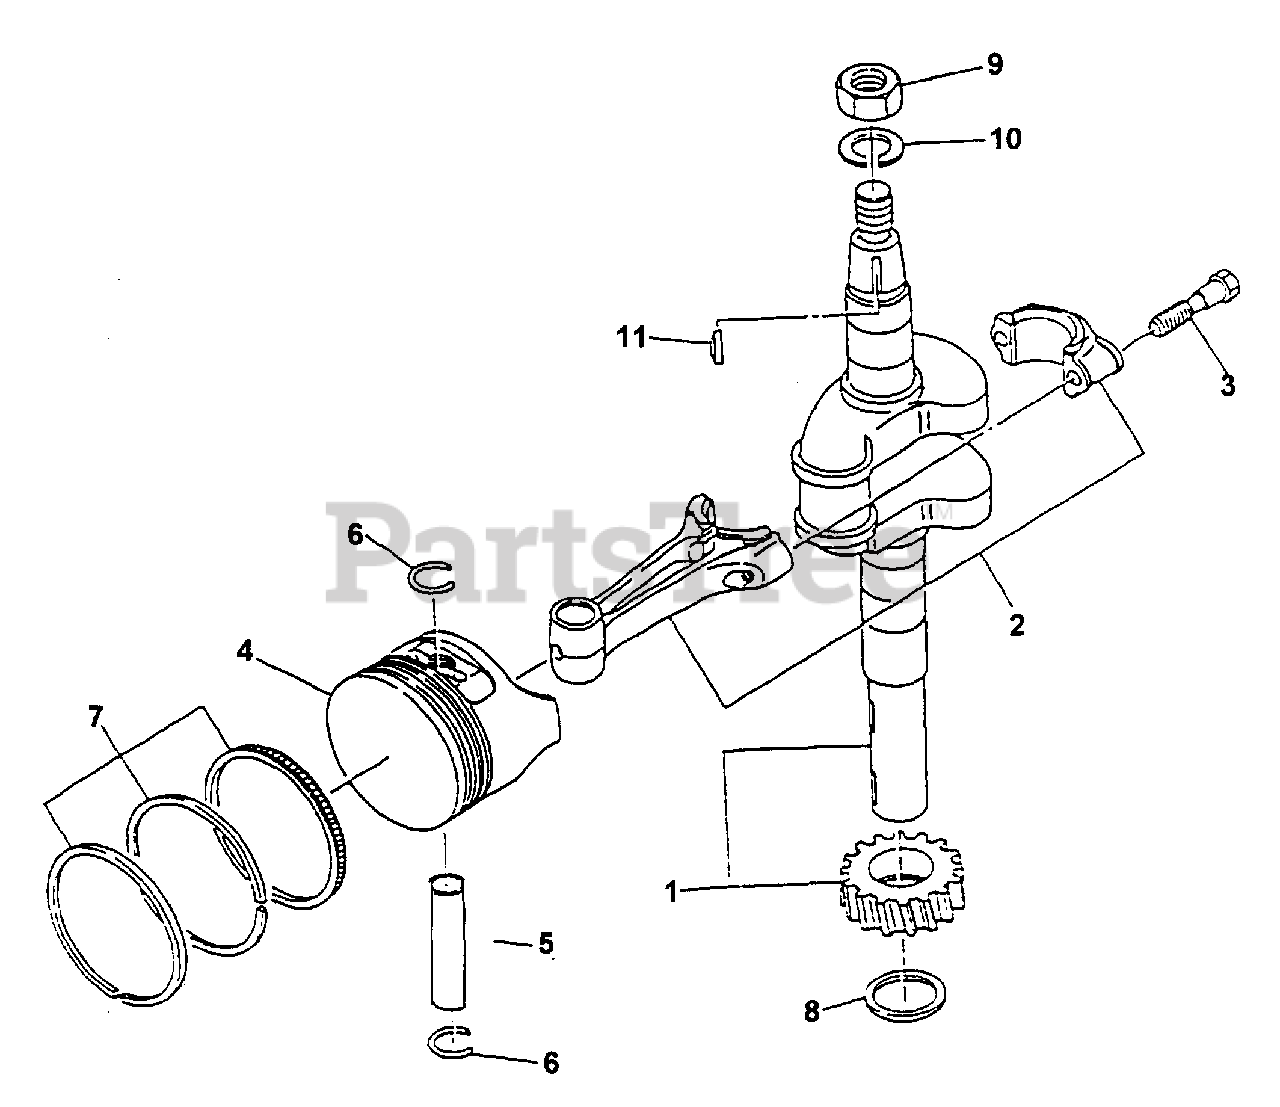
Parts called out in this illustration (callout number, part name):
1	CRANKSHAFT
2	CONNECTING ROD
3	BOLT, Conn. Rod
4	PISTON (Std.)
5	PIN, Piston
7	PISTON RING SET (Std.)
9	NUT
10	WASHER, Spring
11	KEY, Woodruff
